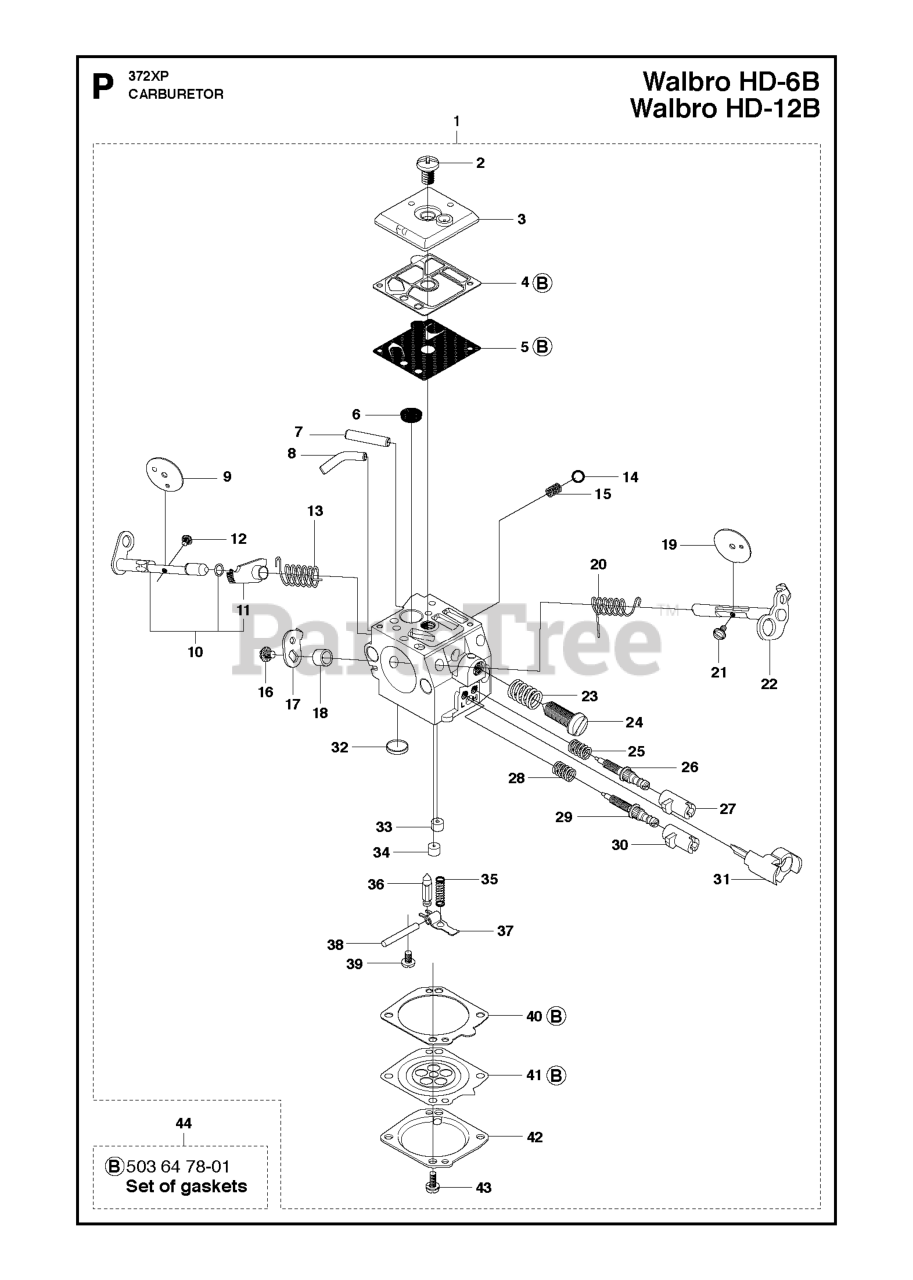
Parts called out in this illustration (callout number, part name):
1	CARBURETOR HD-12B EPA WALBRO
1	CARBURETOR WALBRO HD-6B
4	GASKET, PUMP SIDE
5	PUMP DIAPHRAGM
6	FUEL INLET SCREEN
9	CHOKE FLAP
10	CHOKE SHAFT
19	THROTTLE FLAP
21	SCREW SHUTTERS
23	SPRING
26	IDLE SCREW
26	SCREW
27	LIMITER CAP
29	IDLING SCREW
29	ADJUSTING SCREW
30	LIMITER CAP
31	CAP
32	WELCH PLUG
33	JET
33	NOZZLE
34	JET
35	SPRING
36	INLET NEEDLE
38	FULCRUM PIN
42	IMPULSE COVER
43	RP SCREW W/ WASHER
44	GASKET SET
